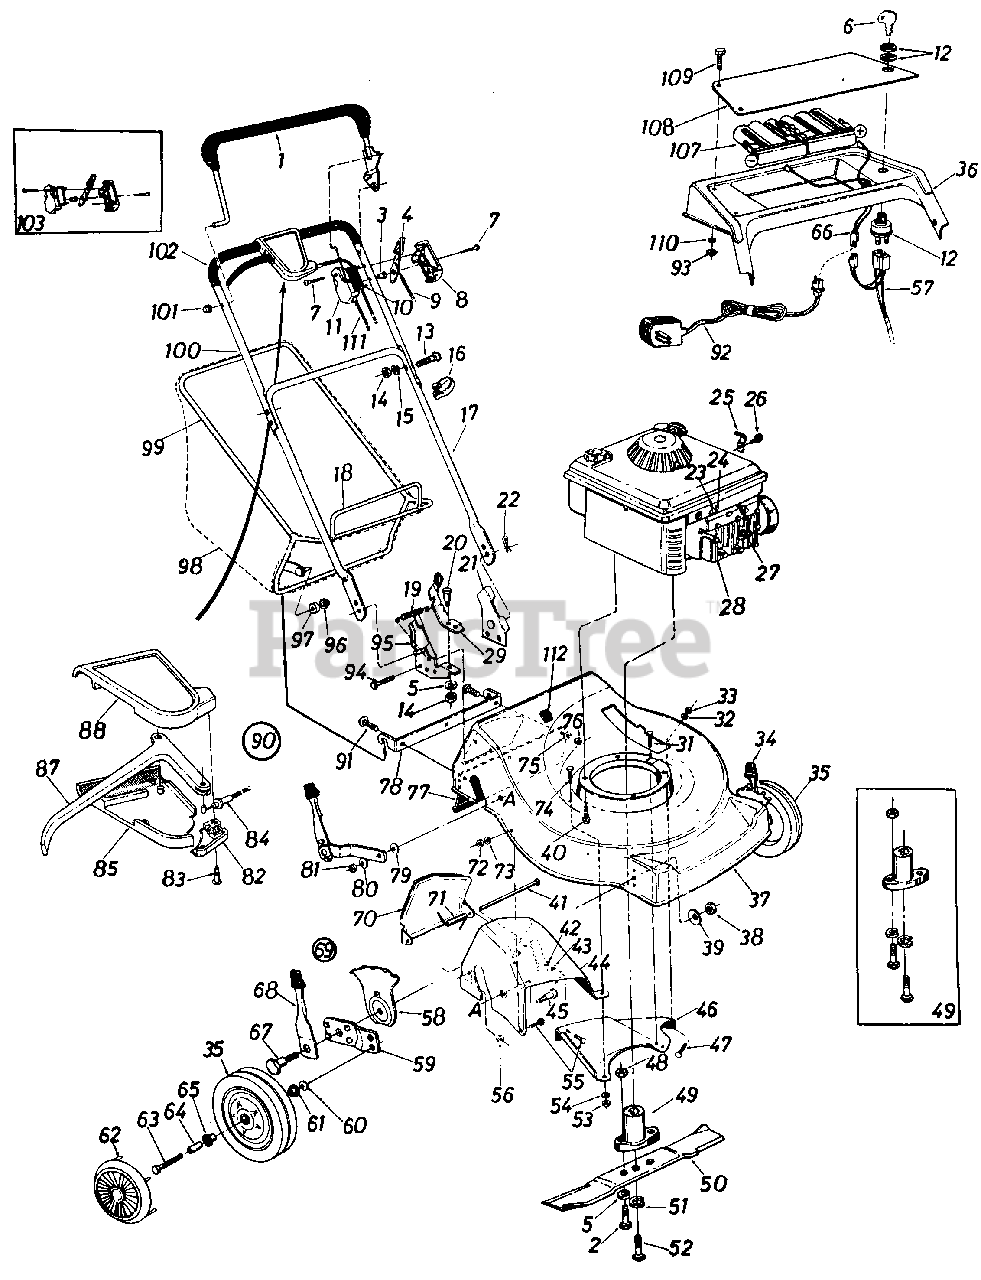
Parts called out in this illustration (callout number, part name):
1	L.H. Bail Ass'y.
2	Hex Bolt 5/16-24 x 1.00" Lg. (Grade 5)
3	Control Disc Pin
4	Throttle Control Lever
5	L-Wash. 5/16" I.D.
6	Ignition Key
7	Truss Mach. Hi-B Tap Scr. #12 x 1.50" Lg.
8	Control Panel Half
9	Throttle Control Wire- 58" Lg.
10	Control Label
11	Clutch Panel Half
12	Ignition Switch
13	Curved Carr. Bolt 5/16-18 x 1.75" Lg.
14	Hex Nut 5/16-18 Thd.
15	L-Wash. 5/16" I.D.
16	Cable Tie
17	Lower Handle
20	Shld. Bolt .437" Dia. x .162
21	Handle Bracket Ass'y.- L. H
22	Hairpin Cotter5/16" Dia.
23	Casing Clamp
24	Hex Sems Scr. #10-32 x .62" Lg.
25	Cable Clip
26	Hex "B"-Tap Scr. #10 x .38" Lg.
27	Spark Plug Insulator
29	L-Wash. 5/16" I.D.
31	Hex TT-Tap Scr. 1/4-20 x .75" Lg.
32	L-Wash. 1/4" I.D.
33	Hex Nut 1/4-20 Thd.
34	Height Adj. Ass'y.-L.H.
35	Front Wheel Ass'y. Comp. 8x 1.75
36	Handle Panel
39	Bell-Wash. .39" I.D. x 1.38" O.D.
40	Hex Wash. Hd. TT-Tap Scr. 3/8-16 x 1.0" Lg.
41	Hinge Pin
42	Hex Nut 1/4-20 Thd.
43	L-Wash. 1/4" I.D.
44	Rear Chute-R.H.
45	Shld. Bolt .500" Dia. x .685
46	Rear Baffle-L.H.
47	Carr. Bolt 1/4-20 x .50" Lg.
48	Hex Nut 5/16-24 Thd.*
49	Blade Adapter Kit
50	22" Blade
51	L-Wash. 3/8" I.D. Heavy Duty
52	Hex Bolt 3/8-24 x 2.25" Lg. (Grade 5)
53	Hex Nut 1/4-20 Thd.*
54	L-Wash. 1/4" I.D.*
55	Carr. Bolt 1/4-20 x .50" Lg.*
56	Hex Sems Nut 1/4-20 Thd.
57	Wire Harness
58	Height Adj. Plate
59	Wheel Pivot Bar
60	Bell-Wash. .40" I.D. x .88" O.D.
61	Flg. Ball Brg. 3/8" I.D.
62	Plastic Hub Cap
63	Hex Bolt 3/8-16 x 1.75" Lg.
64	Spacer.375" I.D. x .505 O.D.
65	Flg. Ball Brg. 1/2" I.D.
66	Battery Pack Lead
67	Shld. Bolt .50" Dia. x.430
68	Spring Lever Ass'y. w/ Knob
69	Height Adj. Ass'y.-R.H.
70	Chute Door
71	Torsion Spring
72	Hex Nut 1/4-20 Thd.*
73	L-Wash. 1/4" I.D.*
74	Hex Bolt 1/4-20 x .88" Lg.
75	Fl-Wash. .285" I.D. x 1.25"O.D.
76	Hex Sems Nut 1/4-20 Thd.
77	Rear Flap
78	Grass Catcher Hitch Brkt.
79	Bell-Wash. .400" I.D. x 1.13" O.D.
80	Bell-Wash. .400" I.D. x .88" O.D.
81	Hex Jam Nut 3/8-16 Thd.
82	Cable Mounting Cap
83	Flat "C"-Sunk Hd. Tap Scr. #10 x .75" Lg.
84	S.P. Cable-43" Lg.
85	Control-Lower Cover
87	Control Lever
88	Control-Upper Cover
90	Clutch Control Housing Comp.
91	Carr. Bolt 1/4-20 x .75" Lg.*
92	Battery Charger
93	Hex Nut #8-32 Thd.
94	Hex Bolt 1/4-28 x .75" Lg.*
95	Handle Bracket Ass'y.-R.H.
96	Push Nut 3/8" Rod
97	Plastic Roller
98	Grass Bag
99	Catcher Upper Frame
100	Upper Handle
101	Cap Speed Nut
103	Control Housing Comp.
107	Battery Pack
108	Battery Plate
109	Fl-Hd. Phil. Scr. #8-32 x .38" Lg.
110	External L-Wash. #8 I.D.
111	Clutch Control Cable 45"
